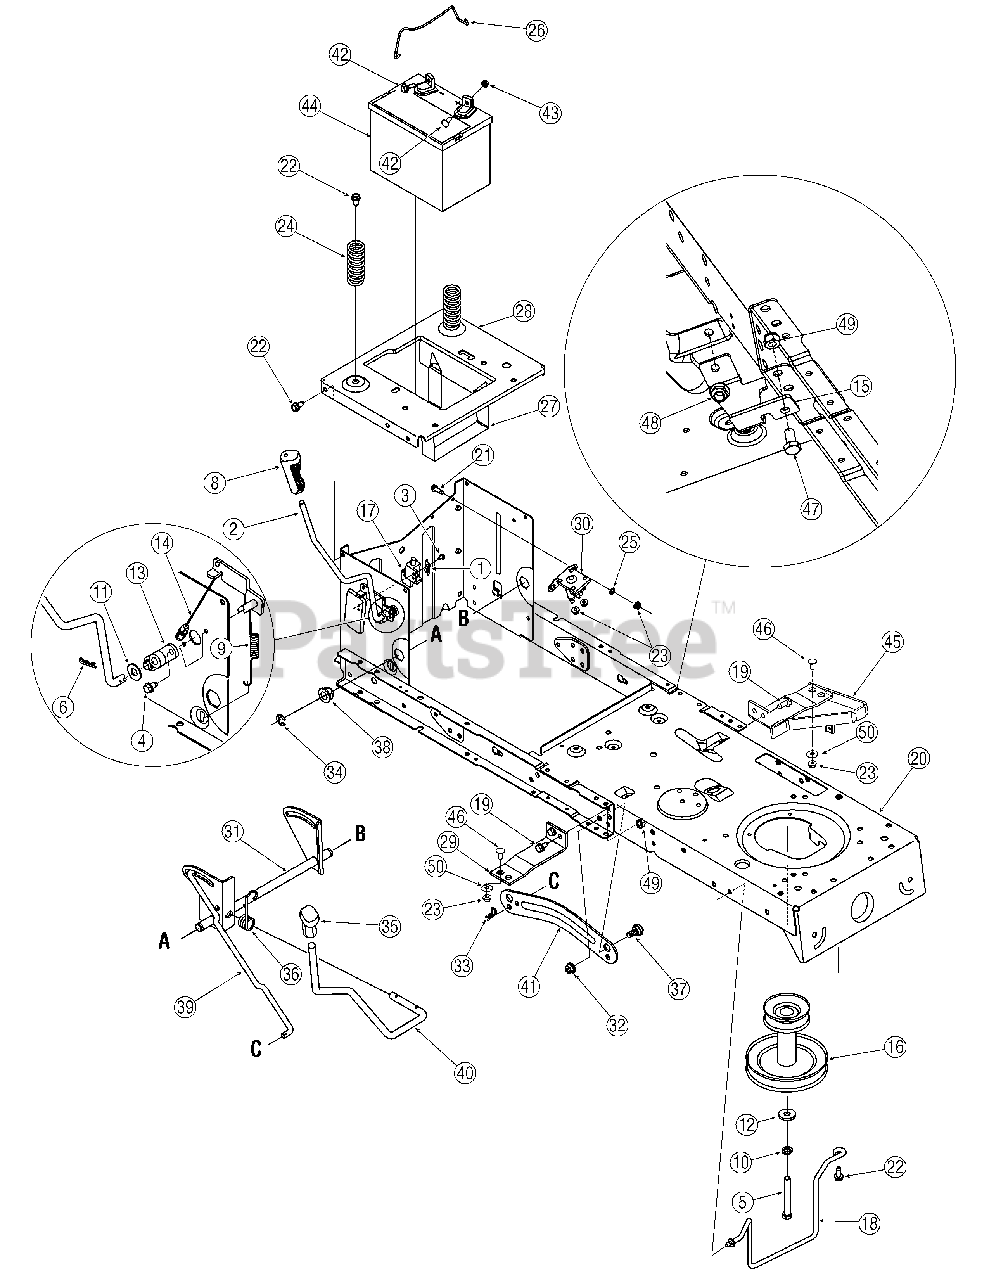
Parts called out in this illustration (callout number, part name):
1	Plate, Switch
3	Screw, #10-16, 0.500
4	Screw, 1/4-20, 0.500
5	Screw, 7/16-20, 3.25, Gr5
6	Pin, Cotter, .072 Dia. x 1.13
7	Pin, Click, .092 x 1.64
8	Grip, Handle, 3/8
9	Spring, Extension
10	Washer, Lock, 7/16
11	Washer, Flat, .406 x .875 x .059
12	Washer, Flat, .450 x 1.250 x .164
13	Bearing, PTO
14	Cable, Deck Engagement
16	Engine Pulley, 3.39 x 6.12
17	Switch, Interlock
18	Rod, Belt Keeper (38-inch Deck)
18	Rod, Belt Keeper (42-inch Deck)
19	Screw, 5/16-18, .750
21	Screw, 1/4-20, 0.750
22	Screw, 5/16-18, 0.625
23	Nut, Flange Lock, 1/4-20, GrF
24	Spring, Compr. , 1.28 OD x 3.125
25	Washer, Lock, 1/4
30	Solenoid
32	Nut, Flange Lock, 3/8-16, GrF
33	Pin, Cotter, .080 x 1.5625 Internal
34	Ring, E-Type, .625 Dia.
35	Grip, Handle, 1/2
36	Spring, Torsion
37	Screw, Shldr. , .625 x .175, 3/8-16
38	Bearing, Hex Flange
39	Rod, Lift
40	Deck Handle, Lift
42	Screw, Carriage, 1/4-20, .75, Gr5
43	Nut, Sems, 1/4-20
44	Battery, 190 CCA
44	Battery, 125 CCA
46	Carriage Screw, 1/4-20 x .62
47	Screw, 5/16-18 x .625
48	Flange Lock Nut, 5/16-18
49	Hex Lock Nut, 5/16-18
50	Flat Washer, .28 x .74 x . .063
